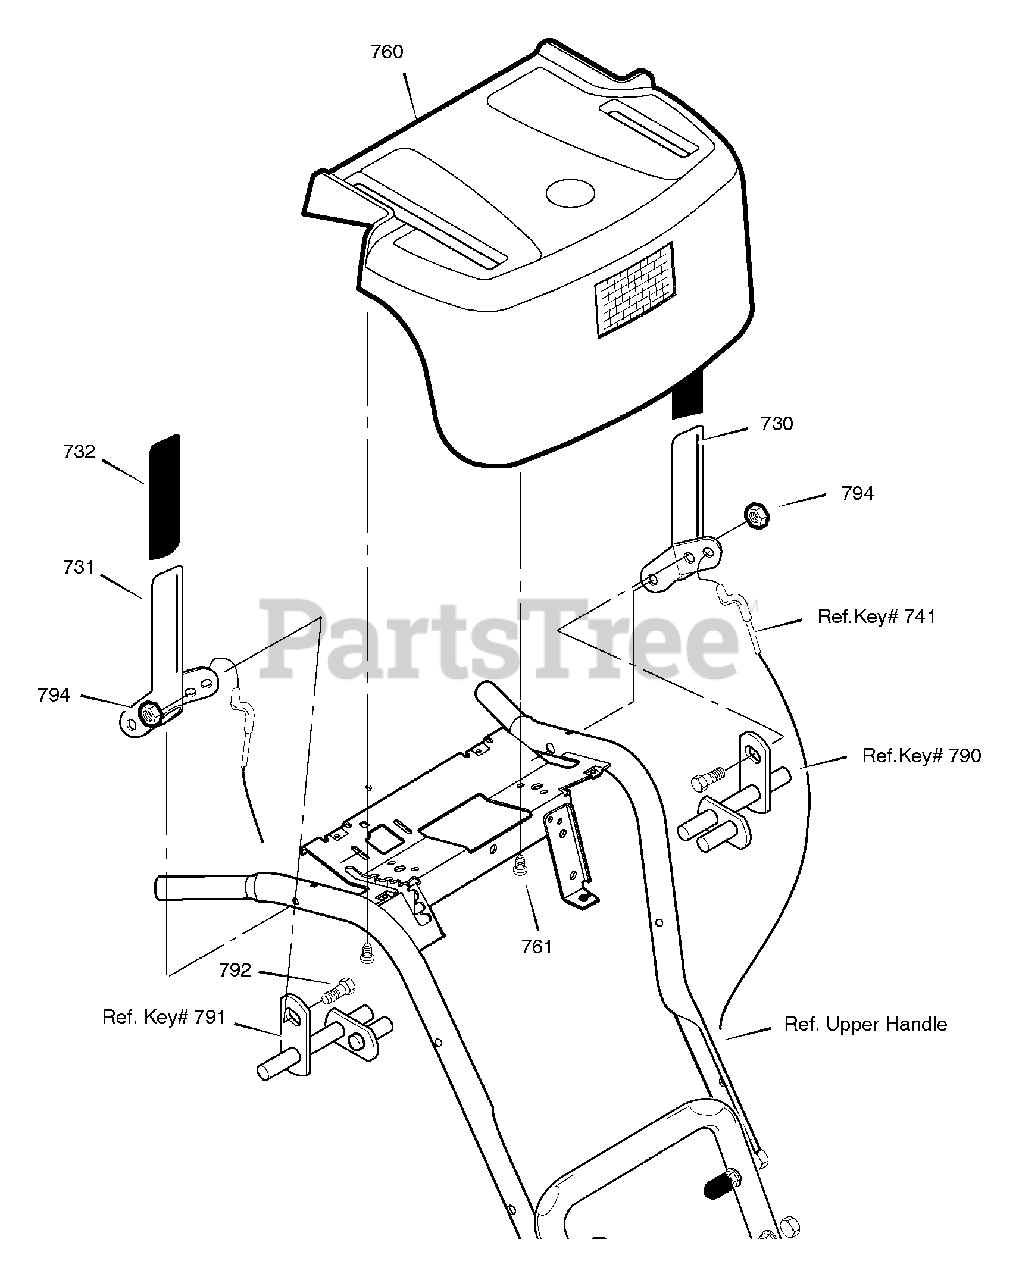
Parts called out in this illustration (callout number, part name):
730	CLUTCH HANDLE LH
731	CLUTCH HANDLE RH
732	GRIP, CLUTCH LEVER
760	PANEL, CONTROL
761	SCREW
792	BOLT, 1/4-20 X 0.50
794	NUT, 1/4-20
